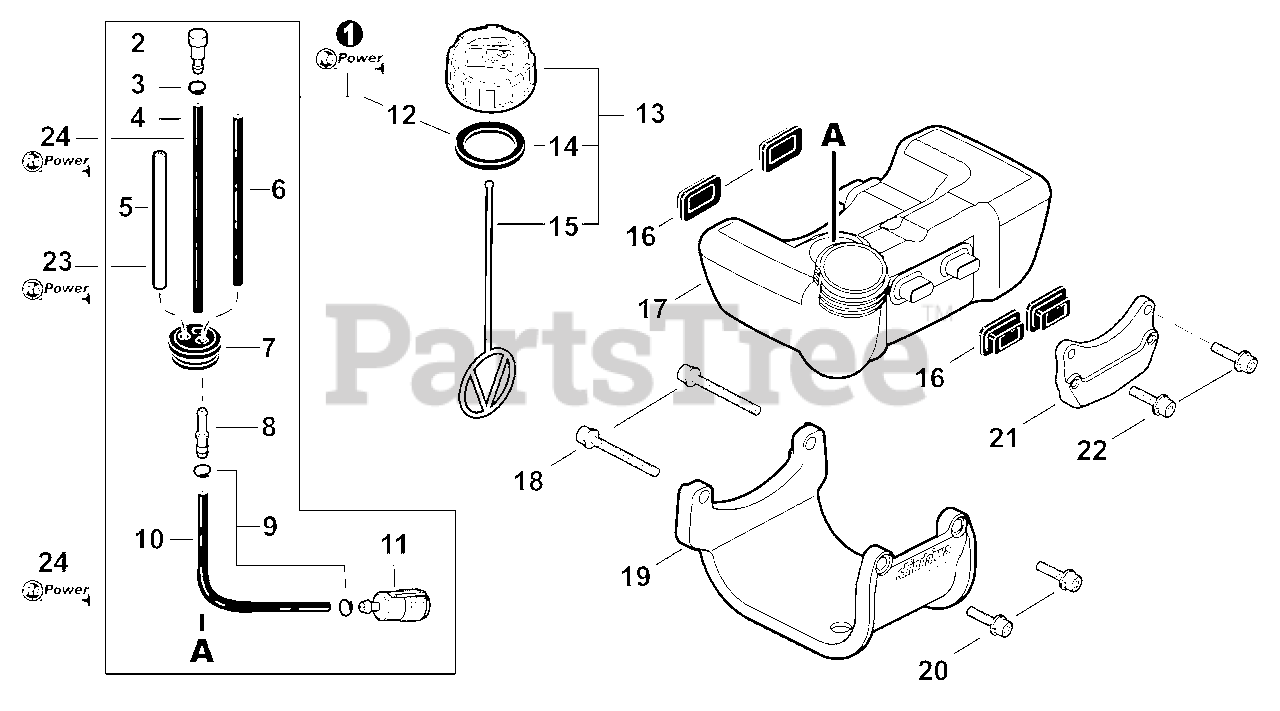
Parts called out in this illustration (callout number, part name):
1	FUEL SYSTEM KIT
2	VENT ASSY
3	CLIP Ø6.5 MM
4	PIPE 3×6×115 BLACK
5	PIPE, FUEL RETURN 3×6×90 MM CLEAR
6	PIPE, FUEL 3×5×78 BLACK
7	GROMMET, FUEL
8	CONNECTOR, PIPE Ø5ר3.5
9	CLIP Ø6
10	PIPE, FUEL 3×6×120 BLACK
11	FILTER, FUEL 125-528
12	GASKET, FUEL CAP
13	CAP ASSY, FUEL
14	GASKET, FUEL CAP
15	CONNECTOR, CAP L= 123
16	CUSHION, FUEL TANK
17	TANK, FUEL
18	BOLT M5×40
19	GUARD, PLASTIC FUEL TANK
20	BOLT M5×20
21	BRACKET, METAL FUEL TANK
22	BOLT, ADHESIVE M5×20
23	BULK PIPE - 3×6 MM CLEAR (4 PIECES×2 M)
24	BULK PIPE - 3×6 MM BLACK (4 PIECES×2 M)
